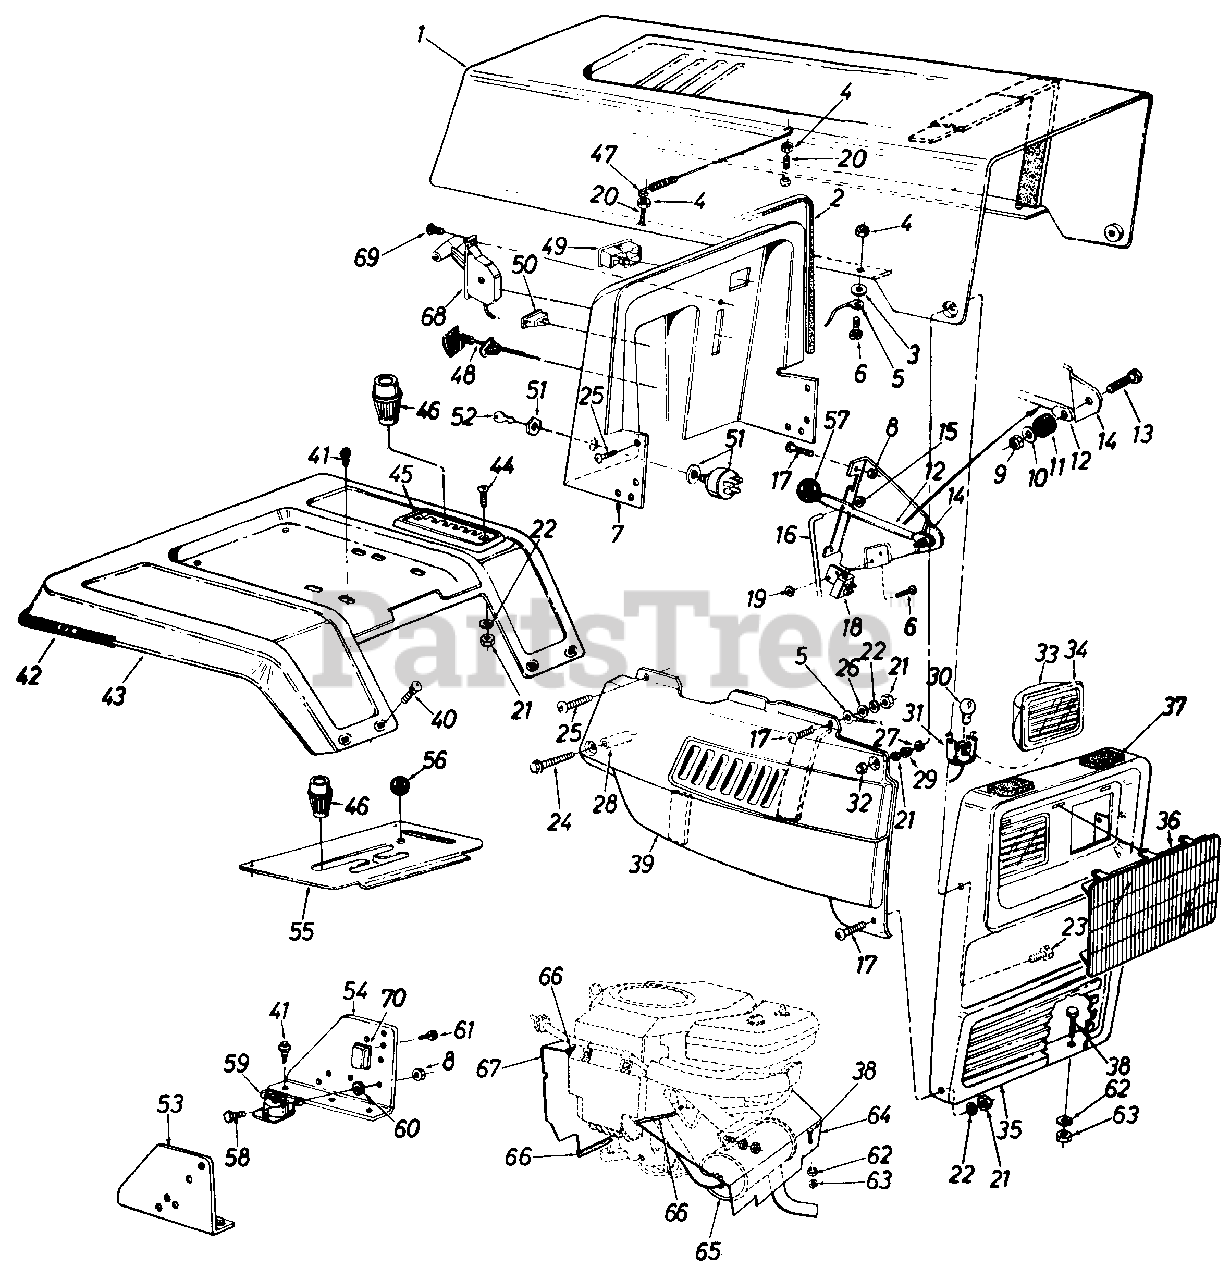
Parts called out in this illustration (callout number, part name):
3	Fl-Wash. .20" I.D. x .41" O.D.
4	Hex Sems Nut #10-.24 Thd.
5	Hood Stop
6	Truss Mach. Scr. #10-24 x .5"Lg.
9	Hex L-Nut 1/4-20 Thd.
10	Fl-Wash. .281" I.D. x .73" O.D.
11	Rubber Washer
12	PTO Lever
13	Hex Bolt 1/4-20 x 1.25" Lg.
14	Deck Clutch Control Brkt.
15	Push Cap
16	Deck Control Rod
17	Truss Mach. Scr. 1/4-20 x .5" Lg
18	Safety Switch
19	Hex Nut #10-24 Thd.
20	Hex Bolt 10-24 x 1.0" Lg.
21	Hex Nut 1/4-20 Thd.
22	L-Wash. 1/4" I.D.
23	Hex Bolt 1/4-20 x .88" Lg.
24	Hex Wash. TT-Tap Scr. 1/4-20 x 1.75" Lg.
25	Hex TT-Tap Scr. 1/4-20 x .75"Lg.
26	Fl-Wash. .25" I.D. x .62"
27	Spr. Wash. .39" I.D. x .62"
28	Spacer .26" I.D. x .375"
29	Shld. Spacer .375" Dia. x .125"Lg.
30	Lamp
31	Socket
32	Acorn Nut 1/4-20 Thd.
33	Headlight Housing
34	Headlight Lens
37	Foam Strip
38	Hex Bolt 5/16-18 x .75" Lg.
41	Hex Wash. AB-Tap Scr. 5/16 x .75" Lg.
42	Trim Strip 81" Lg.
43	Fender
44	Truss Mach. Scr. 1/4-20 x .62" Lg.
45	7-Speed Selector Plate
46	Shift Knob
47	Hood Spring
48	Choke Control 46" Lg.
49	Ammeter
50	Light Switch
51	Ignition Switch
52	Ignition Key
53	Dash Support Brkt. R.H.
54	Dash Support Brkt. L.H.
55	Transmission Cover
56	Ball Knob
57	Knob Blade Clutch
58	Hex Bolt 1/4-20 x .5" Lg.
59	Solenoid
60	Ext. L-Wash. 1/4" I.D.
61	Hex Wash. Hd. Scr. 1/4 x .5" Lg.
62	L-Wash. 5/16" I.D.
63	Hex Nut 5/16-18 Thd.
64	Front Heat Shield
65	Muffler
66	Trim Strip 10" Lg.
67	Rear Baffle
68	Throttle Control Box Ass'y.
69	Truss Mach. AB-Tap Scr. #10 x .5" Lg.
70	Circuit Breaker
